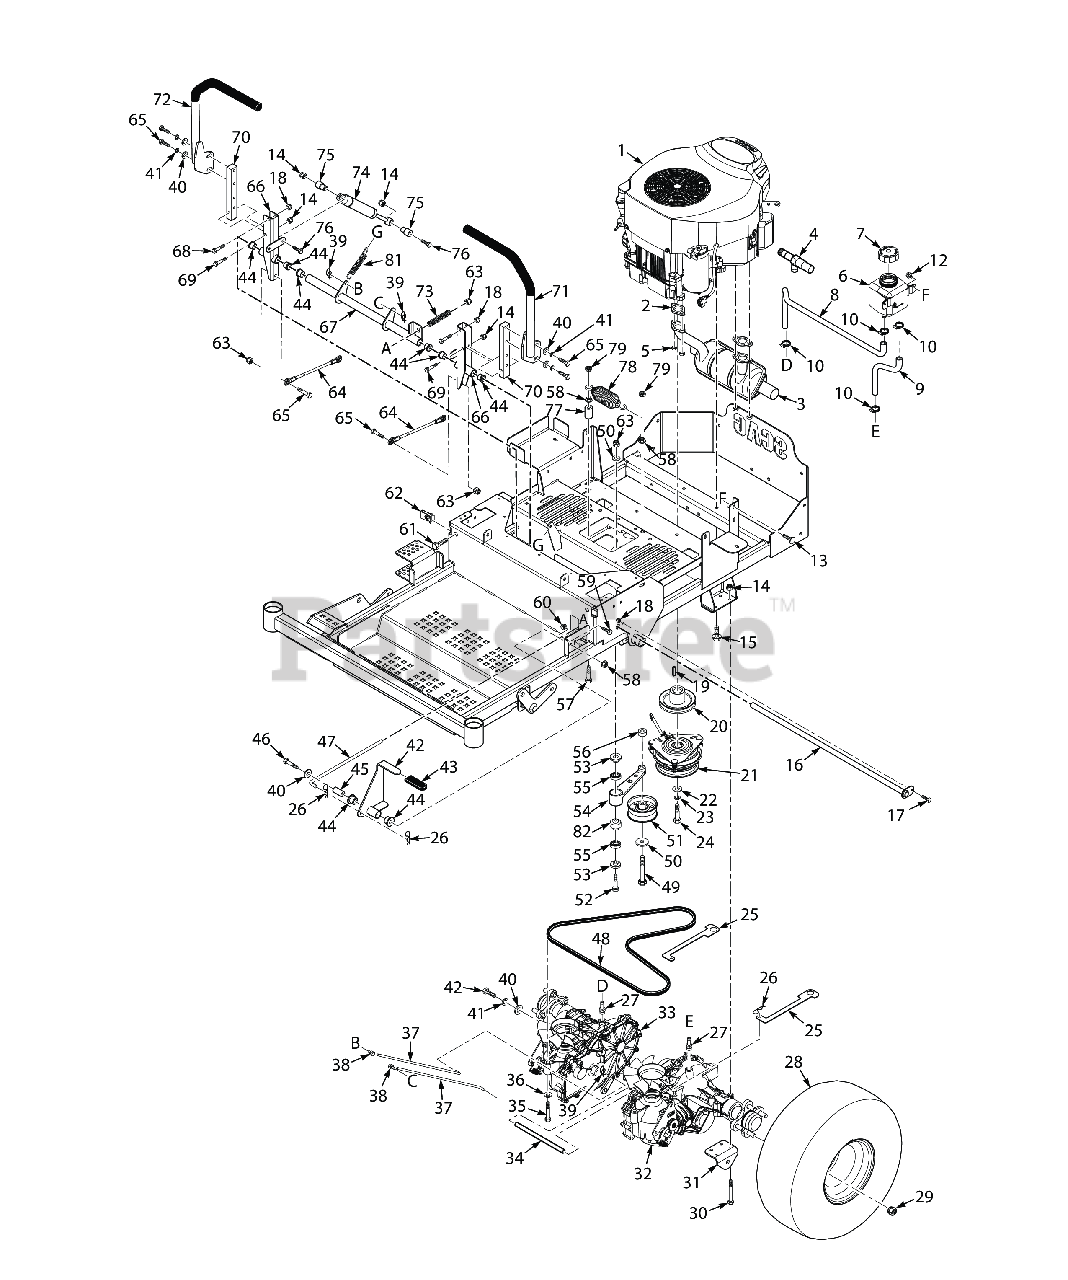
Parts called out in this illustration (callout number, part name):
1	Engine, Kawasaki 21FR
1	Engine, Kawasaki - FR691V
1	Engine, Kohler - 26KT
2	Gasket, Exhaus
3	Muffler, Kawasaki FR651V & FR691V
3	Muffler, Kohler KT
4	Oil Drain, Kawasaki
4	Hose, Oil Drain - Kohler CV & CV-EFI
5	Nut, M6-1.0 Hex Flange
6	Reservoir Assembly
7	Cap, Hydraulic Tank
8	Hose, RH Transmission
9	Hose, LH Transmission
10	Clamp, Cable 3/4" I.D.
11	Clamp, .69" Max. / .25" Min. Dia.
12	Nut, Flanged Elastic Stop 1/4-20
13	Serr. Fl. Hex Head CPSCR, 1/4-20 x 3/4"
14	HEX NUT, ELASTIC STOP LOCK, 5/16-18
15	Bolt, Hex Head Self-Tap 3/8-16 x 1-1/4" (Kohler x3 - 25EFI, Kohler x4 - 29EFI)
16	Shaft Weldment, Control Arm
17	BOLT, HEX HEAD, 1/4-20 X 5/8
18	HEX, NUT, ELASTIC STOP LOCK, 1/4-20
19	Key, 1/4 x 1/4 x 1.25" Pulley Mtg.
20	Pulley, 4-1/2" - 1" Bore
20	Pulley, 4-1/2" - 1.125" Bore (SZL-61)
21	Electric Clutch Assembly
21	Electric Clutch Assembly - SFZ52 & SFZ61
22	Flatwasher, 7/16-.469 x 1.75 x .25 (48, 52)
23	Lockwasher, 7/16� Spring
24	Bolt, Hex Head 7/16-20 x 3" w/t Patch
25	Lever, Dump Valve
26	HAIR PIN, .08 DIAMETER X 1-3/16"
27	Fitting, O-Ring x 3/8" Hose
28	Wheel Assembly (48, 52)
28	WHEEL ASSY, 20 X 10-10
28	Rim w/Valve Stem (48, 52, 61)
28	RIM W/ VALVE STEM
28	Tire, 20 x 10-8 2-Ply (48, 52, 61)
29	Wheel Nut, 1/2-20 x 13/16
30	Bolt, Hex Head 5/16-18 x 3.00"
31	Bracket, Push Arm Link
32	Transaxle, LH - SZL
32	Transaxle, LH - SZL-61
33	Transaxle, RH - SZL
33	Transaxle, RH - SZL-61
34	Spacer
35	BOLT, HEX HEAD, 5/16-18 X 2-1/4
36	Flatwasher, 5/16-.375 x .875 x .083 (35BV & 37BV-EFI)
37	Rod, Brake
38	Joint, Swivel
39	Pin, Rue Cotter 3/8" Diameter
40	Flatwasher, 3/8" Special (.391 x .938 x .105)
41	Lockwasher, 3/8" Spring, Kawasaki FX / FS
42	Bearing
43	Grip, Brake Handle
44	Bearing
45	Pivot, Brake Lever
46	Capscrew, Hex Head 3/8-16 x 2-1/2"
47	Rod, Upper Brake Linkage
48	Belt, Transmission -SZL
49	Capscrew, Hex Head 3/8-16 x 3-3/4"
50	Flatwasher, 3/8 (.391 x .938 x .105 HD) Grade 8
51	Pulley, 3-1/2" Dia.
52	Bolt, Hex Head 3/8-16 x 3" - 52"
53	Spacer, Controls
54	Trans. Idler Arm Assy. (Includes 24, 79)
55	BEARINGS, BALL, NEUTRAL RETURN
56	Spacer, Idler Pulley - SFZ61
57	Capscrew, Hex Head 3/8-16 x 2.0"
58	NUT, 3/8-16 SERRATED FLANGE HEX HEAD
59	Capscrew, Hex Head 1/4-20 x 1"
60	NUT, 1/4-20 SERRATED FLANGE HEX HEAD
61	Bolt, Hex Head 3/8-16 x 2-1/2" Soecial Lock
62	U-Nut, 3/8-16 (short)
63	HEX NUT, ELASTIC STOP LOCK, 3/8-16
64	Linkage, Pump
65	Bolt, Hex Head 3/8-16 x 1-1/4", Kawasaki FX / FS
66	Control Arm Assembly
67	Bellcrank Assembly (incl. 44)
68	Bolt, Hex Head, 1/4-20 x 1-1/4"
69	Bolt, Hex Head 5/16-18 x 1-1/2" - Front
70	Bar, Control Lever
71	Handlebar w/Grip
71	Grip, Control Handle
72	Handlebar w/Grip
72	Grip, Control Handle
73	Spring, Brake
74	Damper, Steering
75	Spacer, Pump Dampener
76	Bolt, Hex Head 5/16-18 x 1-1/2" (Right Front Engine Mounting, Briggs and Kohler Only)
77	Spacer, Idler Pulley - SFZ52
78	Spring, Transmission Drive
79	Bolt, Hex Head 3/8-16 x 1" Ser. Flg.
80	Bolt, Hex Head, 1/4-20 x 1-1/2"
81	Spring, Deck Latch
82	Spacer, Bearing
